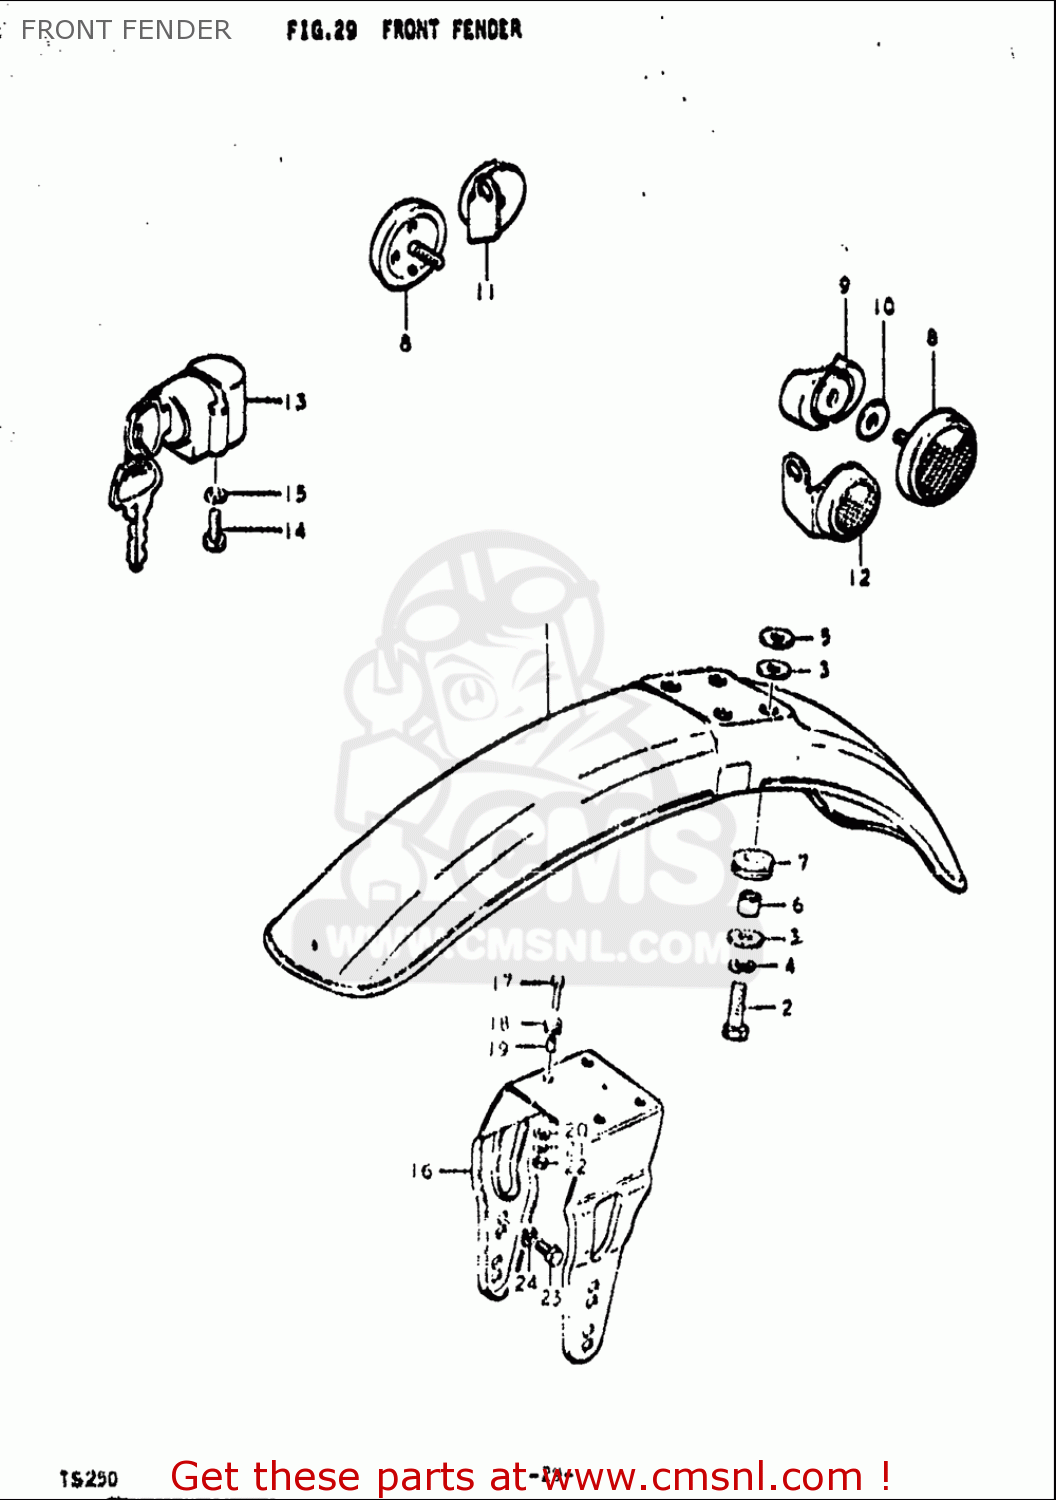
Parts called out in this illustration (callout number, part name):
2	BOLT
3	WASHER(6.5X24X1.2)
4	WASHER,LOCK
5	SPACER (6.5X20X5)
6	SPACER(6.5X10X13.5)
7	CUSHION
8	REFLEX REFLECTOR,RR
9	SPACER
10	WASHER(6.5X20X1.2)
13	LOCK ASSY,STEERING
14	SCREW
15	WASHER,LOCK
17	BOLT
18	CUSHION
19	SPACER(6.1X9X7.5)
20	WASHER(6.5X20X1.2)
22	NUT
23	BOLT
24	WASHER,LOCK
